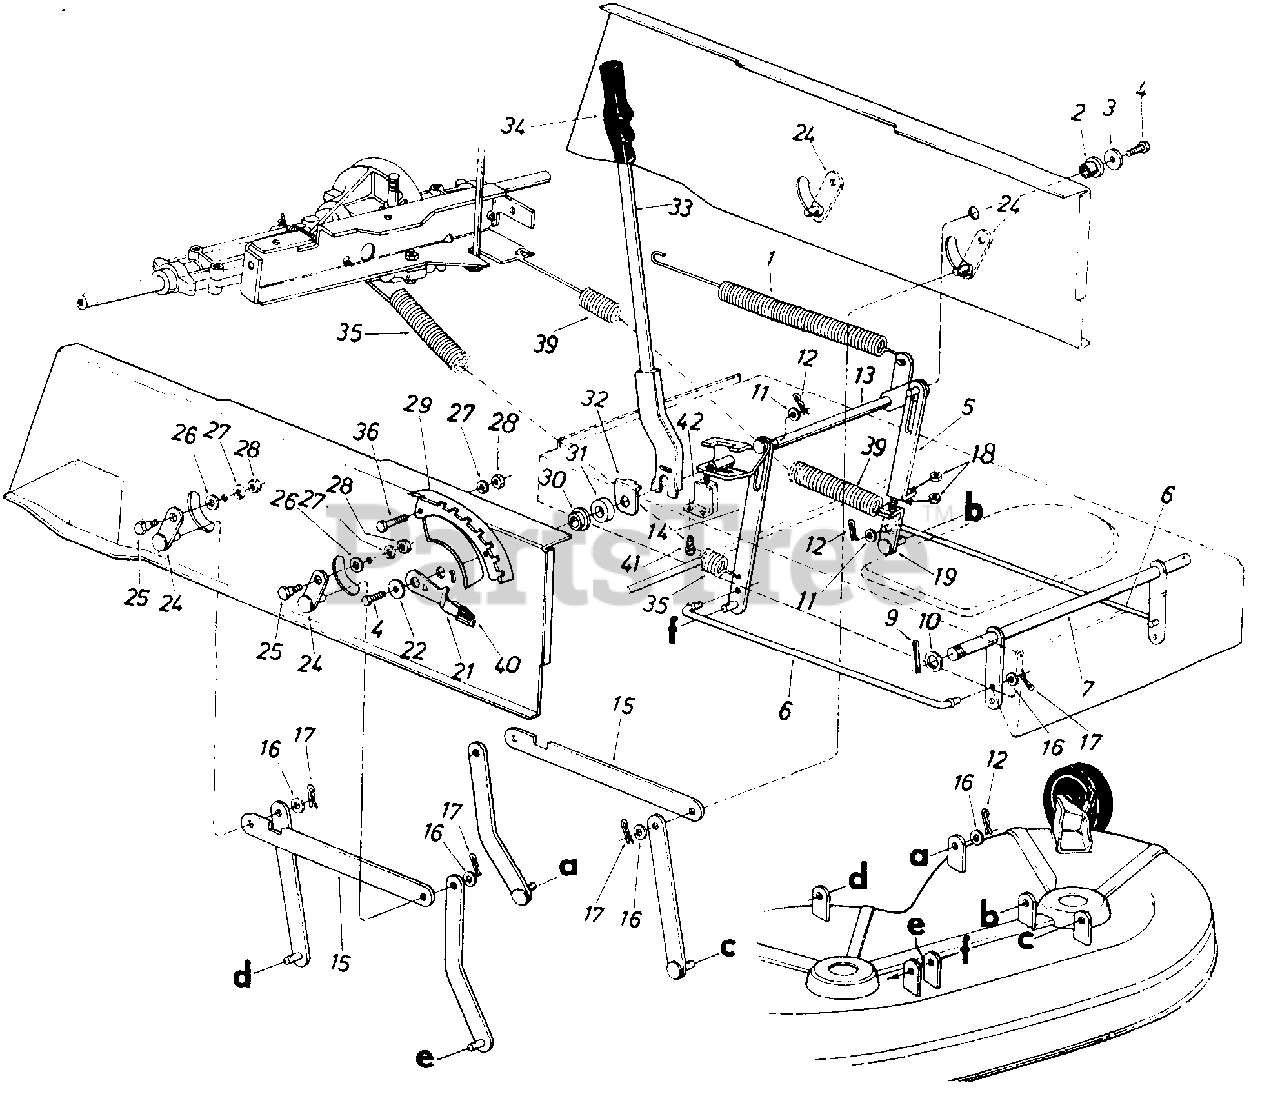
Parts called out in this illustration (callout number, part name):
1	Extension Spring .99" O.D. x 11.00" Lg.
2	Flange Bearing .634" I.D.
3	Fl-Wash. .344" I.D. x 1.125"
4	Hex Wash. Hd. 5/16-18 x .62" Lg.
5	Adj. Link Lift
6	Stabi I izer Rod
7	Stabilizer Shaft Ass'y.
9	Cotter Pin 1/8" Dia. x 1-1/4"
10	Fl-Wash. .635" I.D. x 1.12"
11	Fl-Wash. .531" I.D. x .940"
12	Inter. Cotter Pin .50" Dia.
15	Connecting Rod
16	Fl-Wash. .40" I.D. x .88"
17	Inter. Cotter Pin-3/8" Rod
18	Hex Jam Nut 3/8-16 Thd.
19	Adj. Link Lift Ass'y.
21	Deck Lift-Down Stop
22	Fl-Wash. .344" I.D. x 1.125" O.D. x .125
24	Pivot Link Ass'y.
25	Shld. Bolt .437" Dia. x .180" Lg. (5/16-18)
26	Fl-Wash. .344" I.D. x .62"
27	L-Wash. 5/16" I.D.*
28	Hex Nut 5/16-18 Thd.*
29	Index Brkt.
30	Flange Wash. .628" I.D. x 1.25" O.D.
31	Rubber Wash. 1.50" O.D.
32	Retainer Washer-Lift Handle
33	Lift Handle Ass'y.
34	Grip
35	Extension Spring .99" O.D. x 14.25" Lg.
36	Hex Bolt 5/16-18 x .75"*
39	Extension Spring
40	Knob
41	Hex AB-Tap Scr. #10 x .50"
42	Safety Switch
